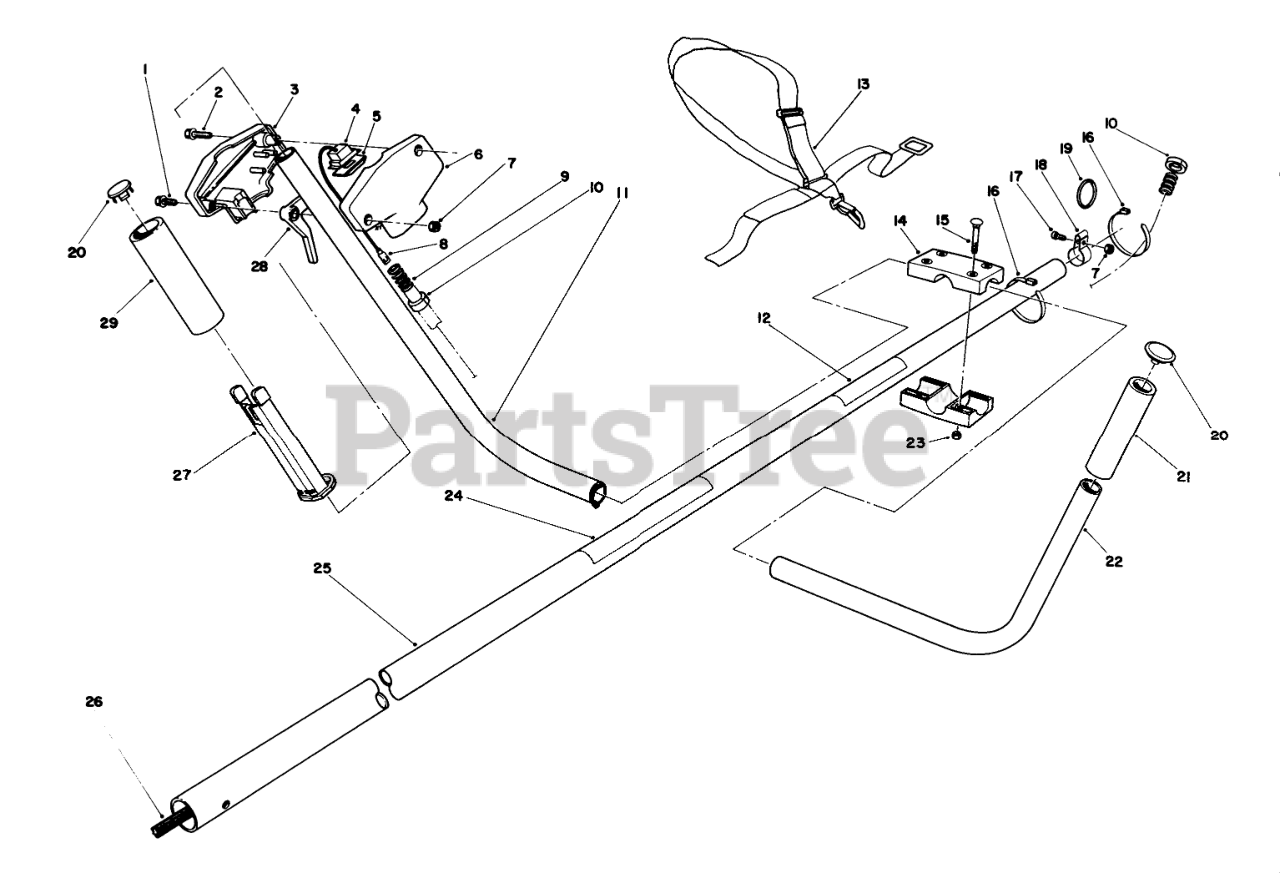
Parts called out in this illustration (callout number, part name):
1	SCREW-HWH
3	THROTTLE HSG R H 1"
4	SWITCH
5	SWITCH COVER-BLACK
6	THROTTLE HSG L H 1"
7	NUT-LOCK, NI
8	WIRE ASM
9	Cover-Cable
10	RING FITTING
11	RH HANDLE
12	Decal
13	Deluxe Harness
14	CLAMP
15	Carriage Bolt
16	TIE-CABLE
17	SCREW-SRH
18	HARNESS CLAMP
19	RING-HARNESS
20	TUBE CLOSURE
21	FOAM GRIP
22	LH HANDLE
23	NUT-LOCK, NI
24	DECAL
25	TUBE ASSEMBLY
26	SPLINED SHAFT
27	TROUGH
28	THROTTLE LEVER
29	GRIP-RUBBER
